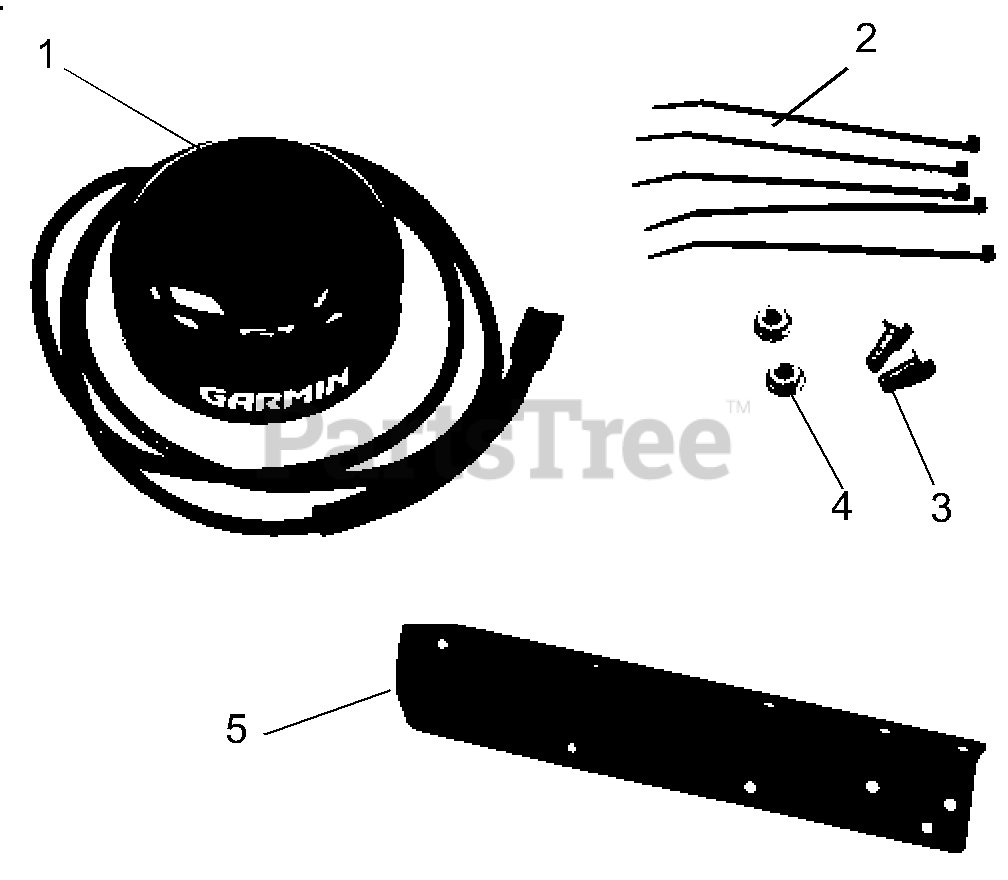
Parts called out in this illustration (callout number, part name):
1	HARNESS, EYE-Q GPS (100S)
2	CABLE TIE LG 5-1/2
3	@BLT-HEX .31-18X.75 GR5 YWZC
4	@NUT-LK-TOP-FLG .31-18 YWZC
5	BRKT, EYE-Q GPS MOUNTING
